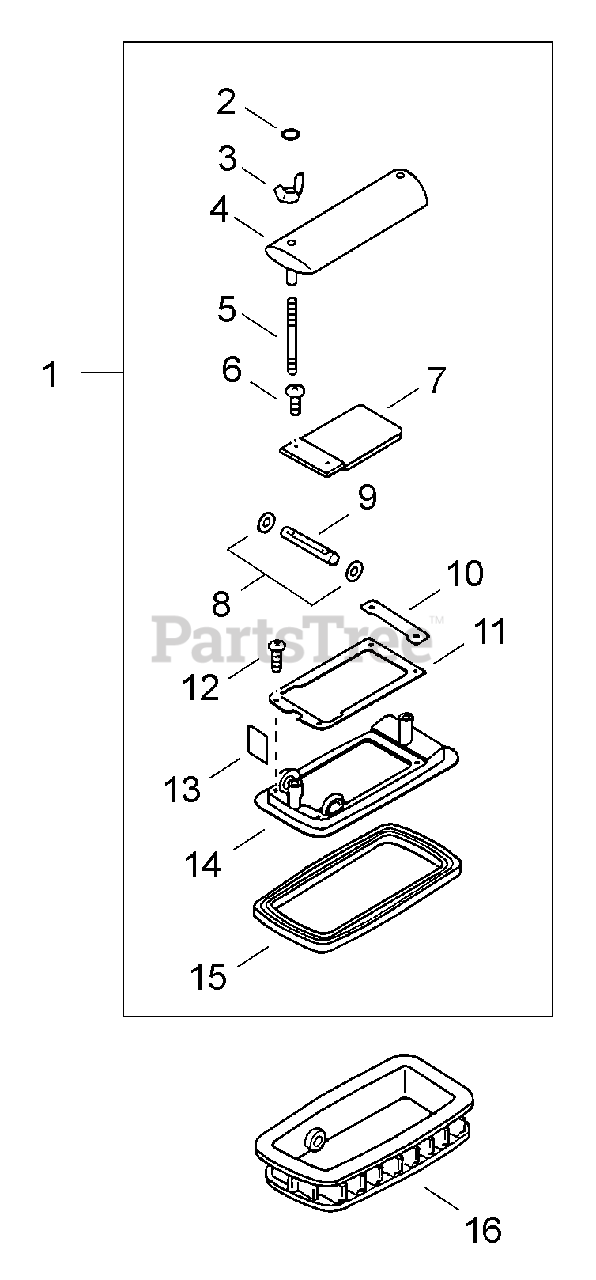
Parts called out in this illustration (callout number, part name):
1	SHUTTER ASSY
3	NUT, WING M5
4	STABILIZER
5	BOLT, STUD 5×50
6	SCREW 4×10
7	SHUTTER, METERING
8	WASHER 10×19.5×0.3
9	SHAFT, SHUTTER
10	PLATE, EYE
11	SHUTTER, METERING
12	SCREW 4×14
14	BODY, SHUTTER
15	GASKET, SHUTTER
16	TANK, LOWER
